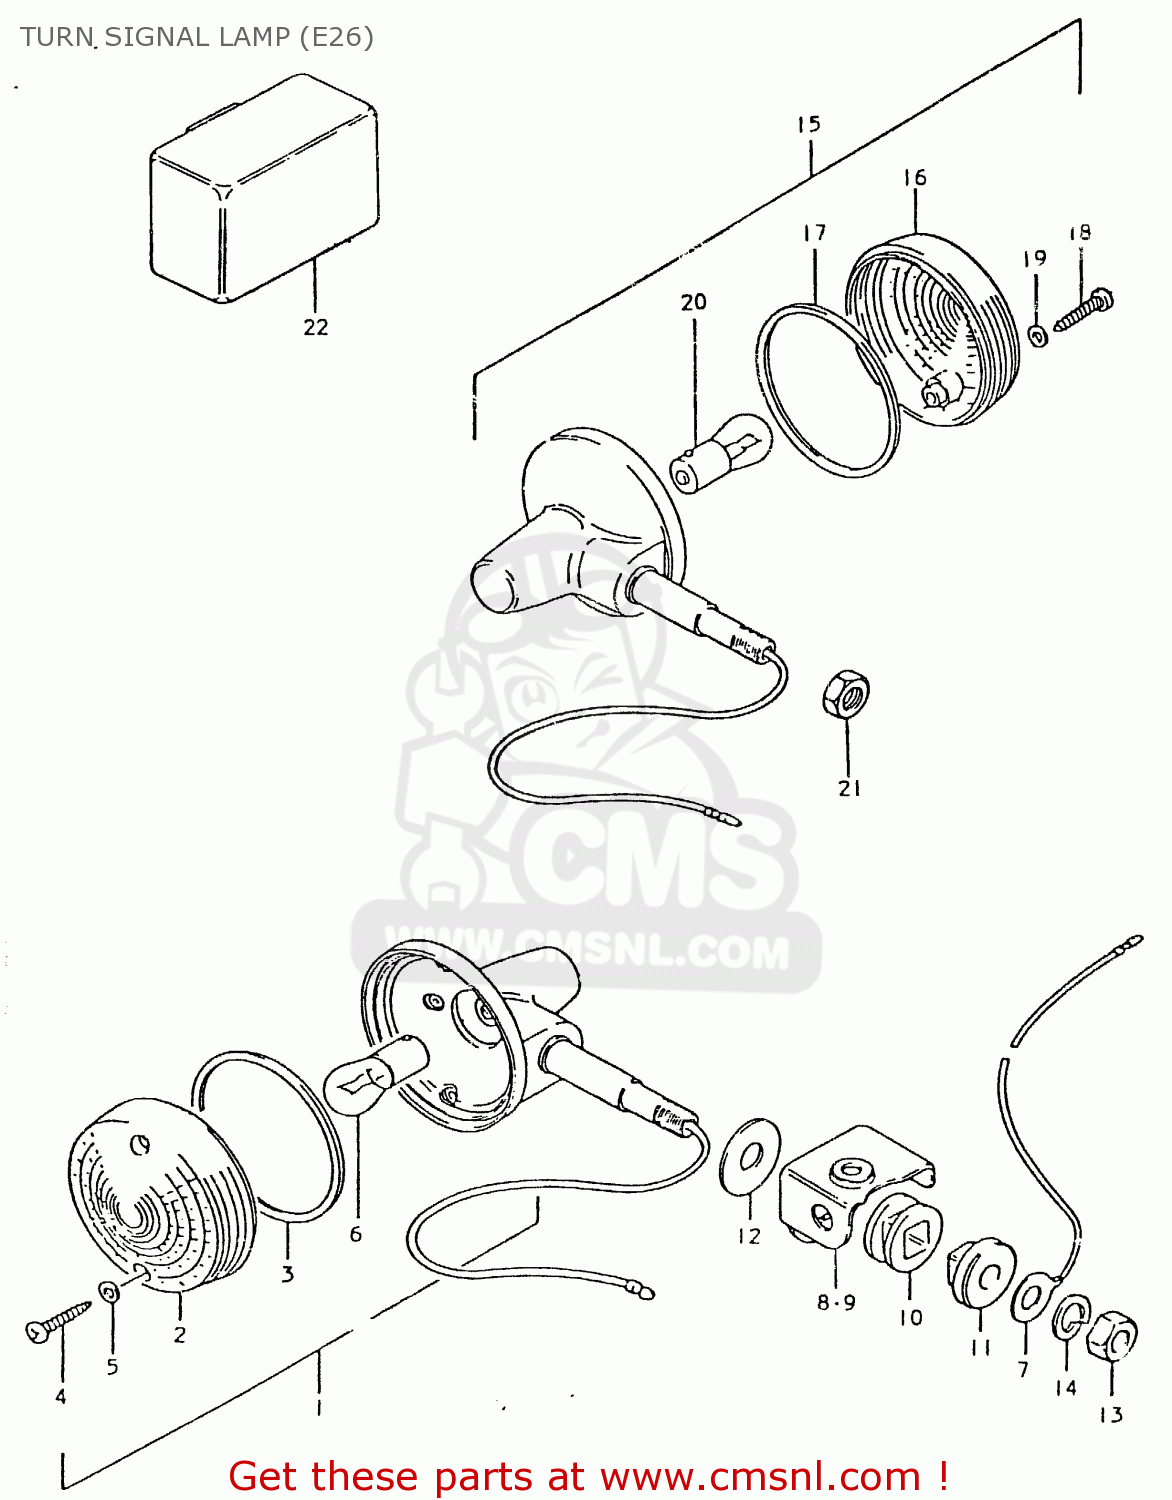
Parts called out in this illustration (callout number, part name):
1	LAMP ASSY,RR TURNSIGNAL
2	LENS
3	GASKET (NAS)
4	SCREW
5	GASKET (NAS)
6	BULB(6V/10W,STANLEY,A4117)
7	LEAD WIRE,EARTH
8	BRACKET, FRONT RH
9	BRACKET, FRONT LH
10	CUSHION
11	SPACER,RR TURNSIGNAL LAMP
12	WASHER (10.5X30X2.3)
13	NUT
14	LOCK WASHER
15	LAMP ASSY,RR TURNSIGNAL
16	LENS
17	GASKET (NAS)
18	SCREW
19	GASKET (NAS)
20	BULB(6V/10W,STANLEY,A4117)
21	NUT
22	RELAY, TURN SIGNAL
